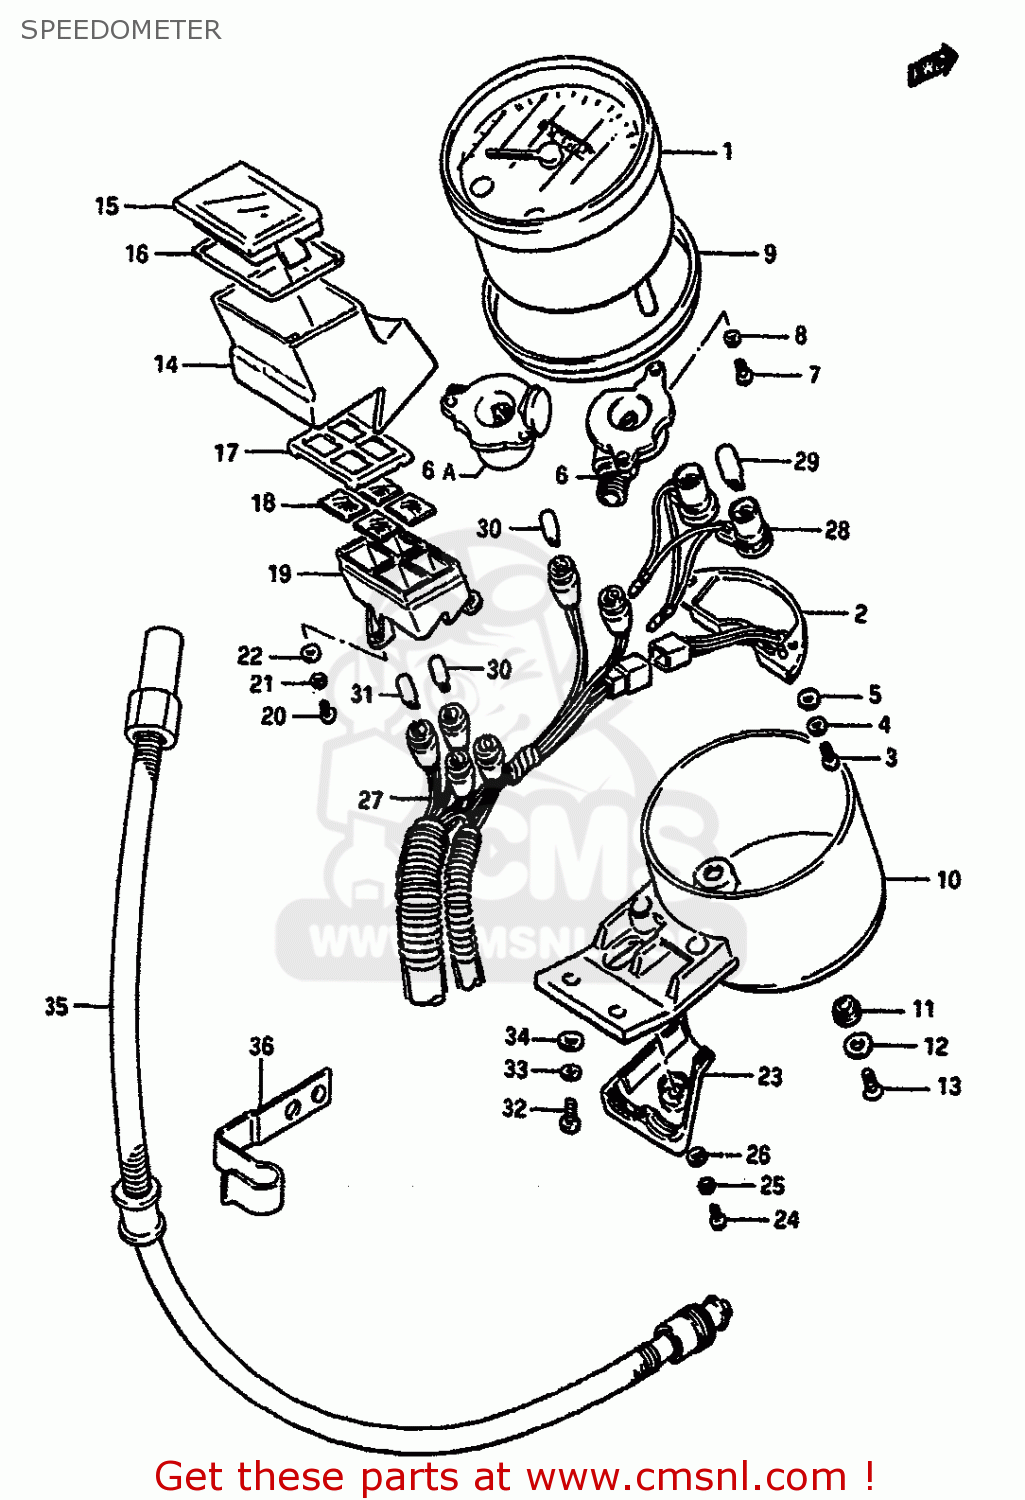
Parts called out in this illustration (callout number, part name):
1	SPEEDOMETER (KILO)
2	UNIT,WATER TEMP
3	SCREW
4	LOCK WASHER
5	WASHER 3.3X8X0
6	BOX,GEAR
6A	BOX,METER GEAR
7	SCREW 4X10
8	WASHER,LOCK 4M
9	CUSHION
10	COVER,METER
11	CUSHION,METER
12	WASHER
13	SCREW
14	BOX,PILOT
15	LENS,PILOT BOX
16	CUSHION
17	PLATE,PILOT LENS
18	LENS SET
19	CASE,PILOT LAMP
20	SCREW
21	LOCK WASHER
22	WASHER 3.3X8X0
23	COVER,PILOT BOX
24	SCREW
25	WASHER,LOCK 4M
26	WASHER 4MM
27	SOCKET,METER NO.1
28	SOCKET
29	BULB(12V3.4W,T10)
30	BULB(12V3W,T6.5)
31	BULB(12V1.7W,T6.5)
32	SCREW
33	WASHER,LOCK
34	WASHER
35	CABLE ASSY,SPEEDOMETER
36	CLAMP,SPEEDOMETER CABLE
